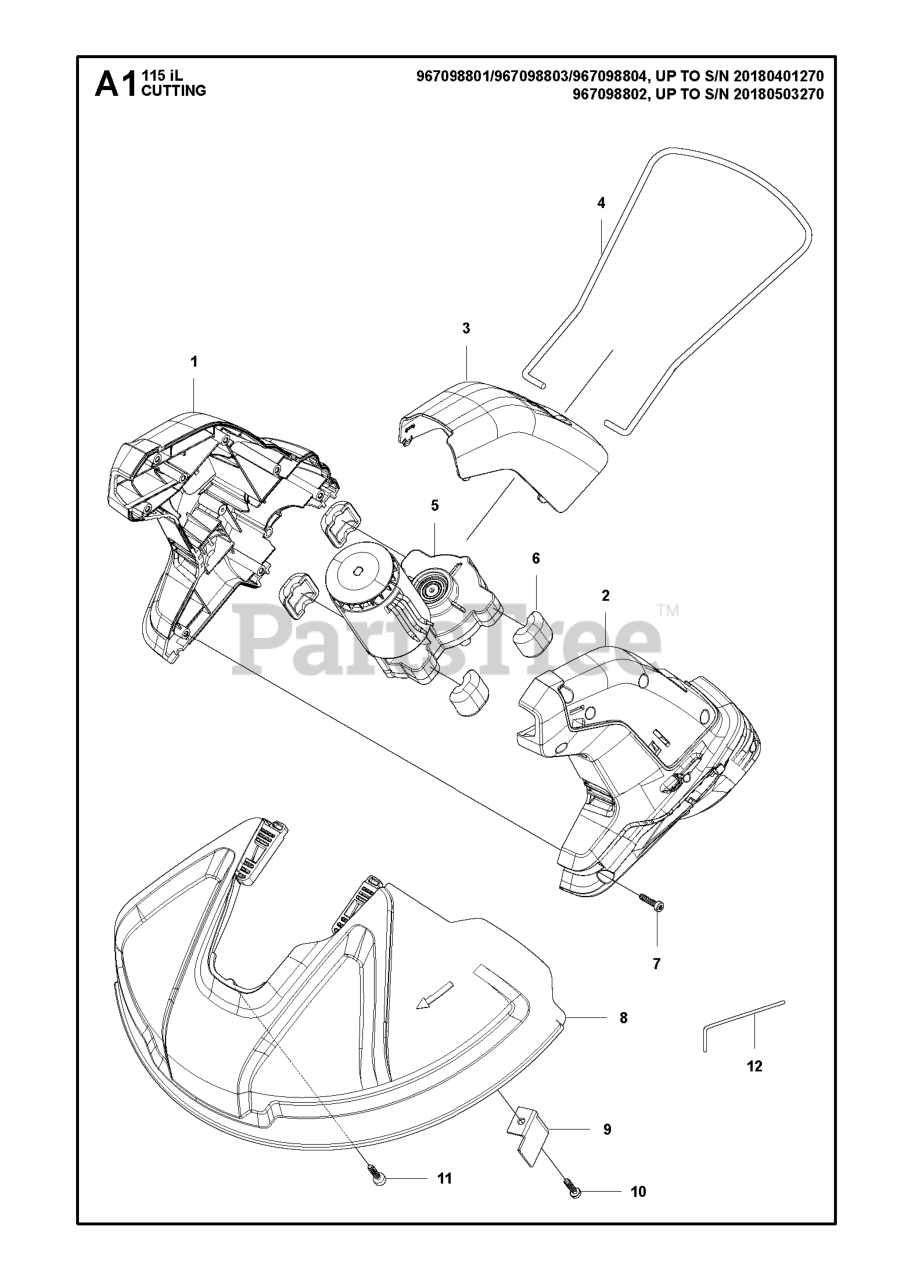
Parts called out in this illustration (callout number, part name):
1	HOUSING MOTOR HOUSING L 36V
2	HOUSING MOTOR HOUSING R 36V
3	COVER MOTOR HOUSING
4	RING PLANT GUARD
5	GEARBOX ASSY 36V
7	SCREW ST4X16
8	GUARD FOR CUTTING HEAD
9	BLADE 330MM
10	SCREW ST4X16
11	SCREW ST4*16
